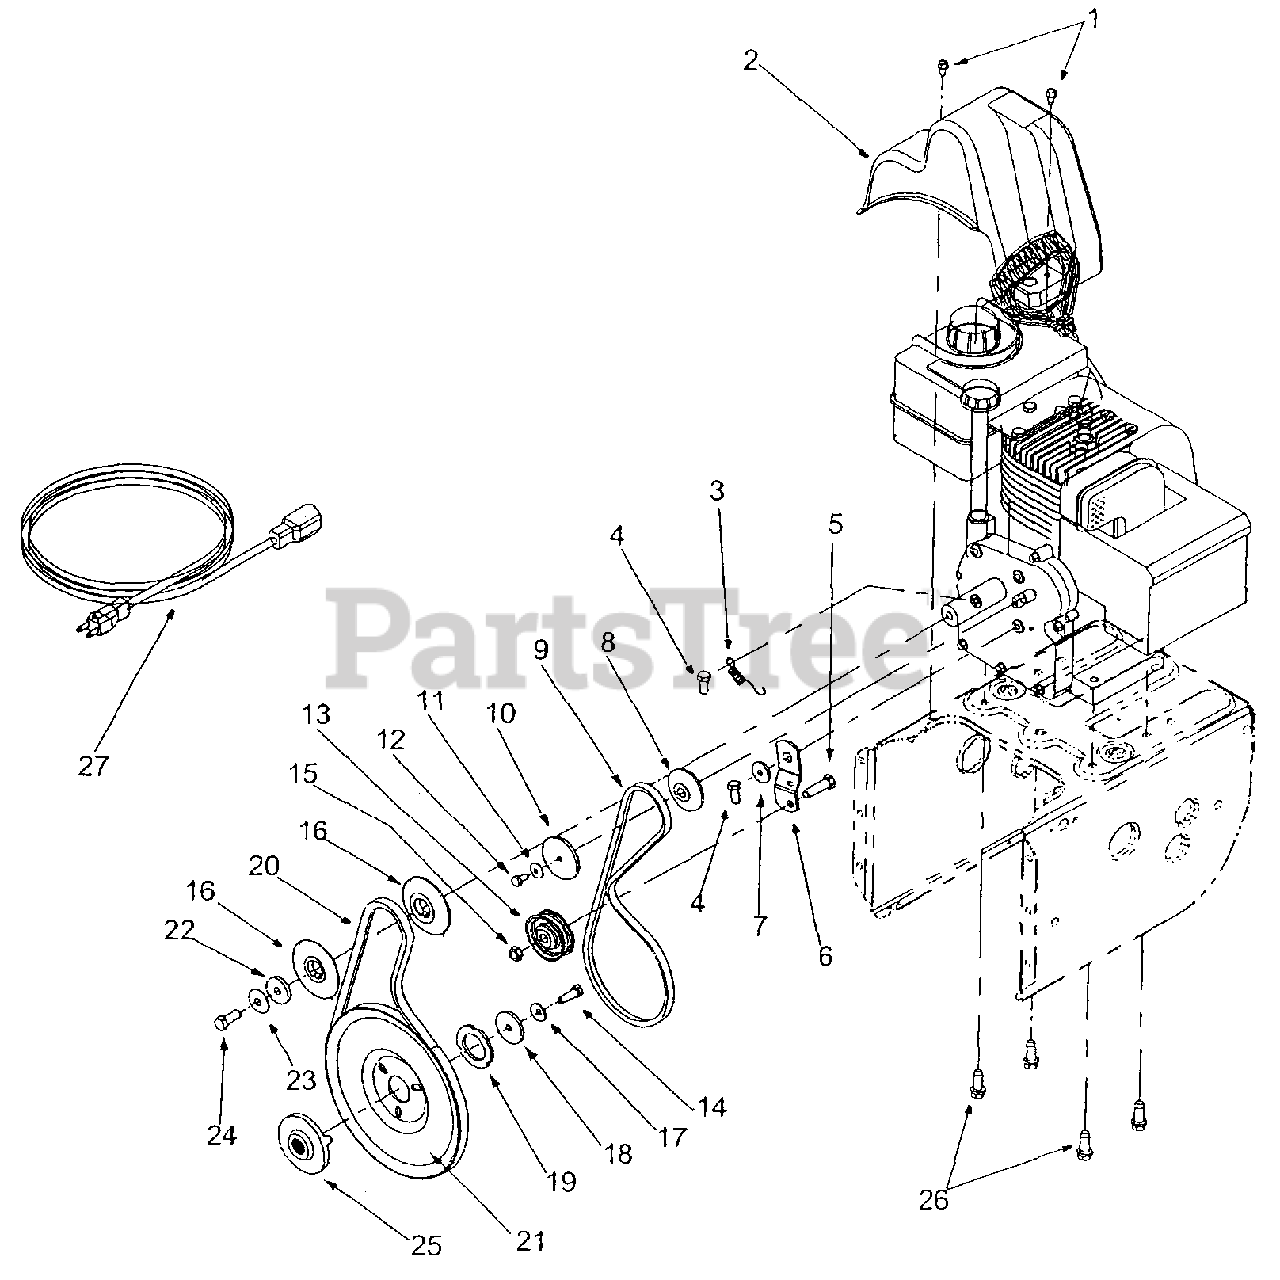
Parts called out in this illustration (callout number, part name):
1	Hex Washer Screw 1/4-20 x.5
2	Belt Cover
3	Extension Spring
4	Hex Screw 5/16-24 x .75
5	Hex Cap Screw 3/8-16 x 1.25
8	Pulley Half
9	V-Belt
10	Pulley Half
11	Bell Washer
12	Hex Cap Screw 1/4-28 x .50
13	Flat Idler
14	Lock Cap Screw 5/16-24
15	Lock Jam Nut 3/8-16
16	Pulley Half
17	Bell Washer
18	Flat Washer
19	Washer
20	Belt
21	Auger Pulley
22	Flat Washer
23	Bell Washer
24	Hex Cap Screw 3/8-24
25	Pulley
26	Hex Washer Screw 3/8-16 x 1.0
27	Extension Cord
